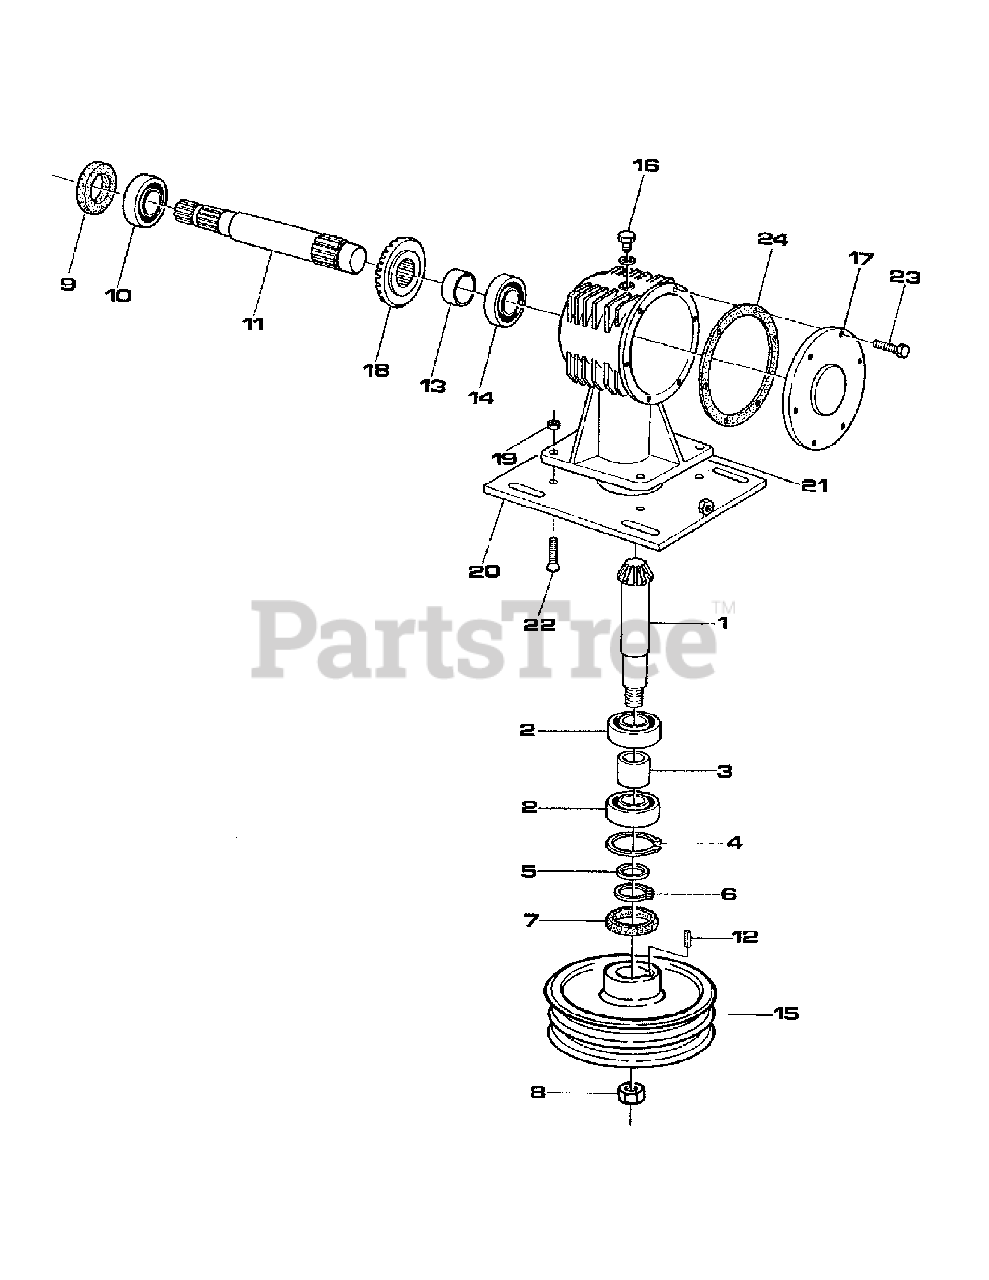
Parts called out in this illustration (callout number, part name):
1	Pinion Gear
2	Bearing 6208
3	Spacer
4	Inner snap ring Ø80
5	Spacer washer
6	Outer snap ring Ø40
7	Oil seal 40.80.10
8	Nut M25
9	Oil seal 35.62.10
10	Bearing 6207
11	Input shaft
12	Key 8x7x30
13	Rear spacer
14	Bearing 30206
15	Pulley SPB 250x2
16	Breather cap
17	Gear cover
19	Nut M12
20	Gearbox support plate
21	Gearbox housing
22	Bolt TSPEI 12x40
23	Bolt TE 10x20
24	Gasket (0.012)
24	Gasket (0.028)
